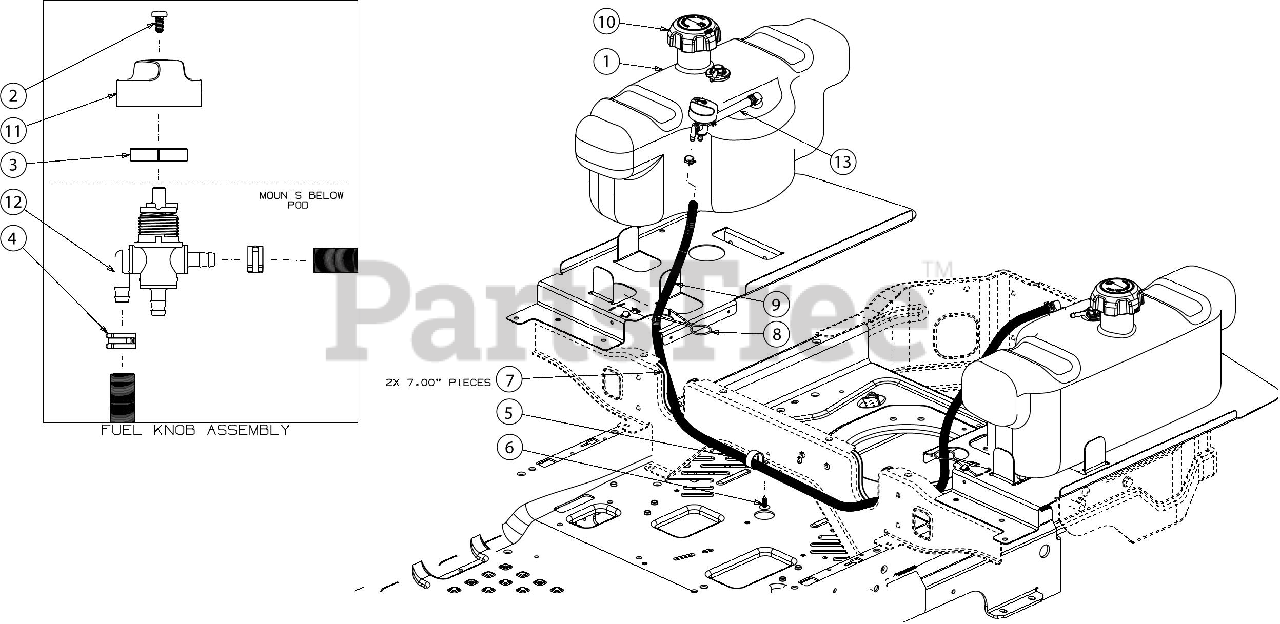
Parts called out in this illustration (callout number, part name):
1	FUEL TANK ASSEMBLY
2	SCREW-M4-0.7 x 8MM
3	3 WAY SELECT NUT
4	HOSE CLAMP 1/20
5	DRAIN HOSE CLAMP
6	RATCHET CLIP .250
7	TRIM STRIP
8	TANK SUPPORT ROD
9	FUEL HOSE LOW PERMEATION
10	FUEL CAP W/TETHER
11	FUEL CAP 3 WAY
12	3-WAY FUEL SELECT SWITCH
13	FUEL HOSE LOW PERMEATION
